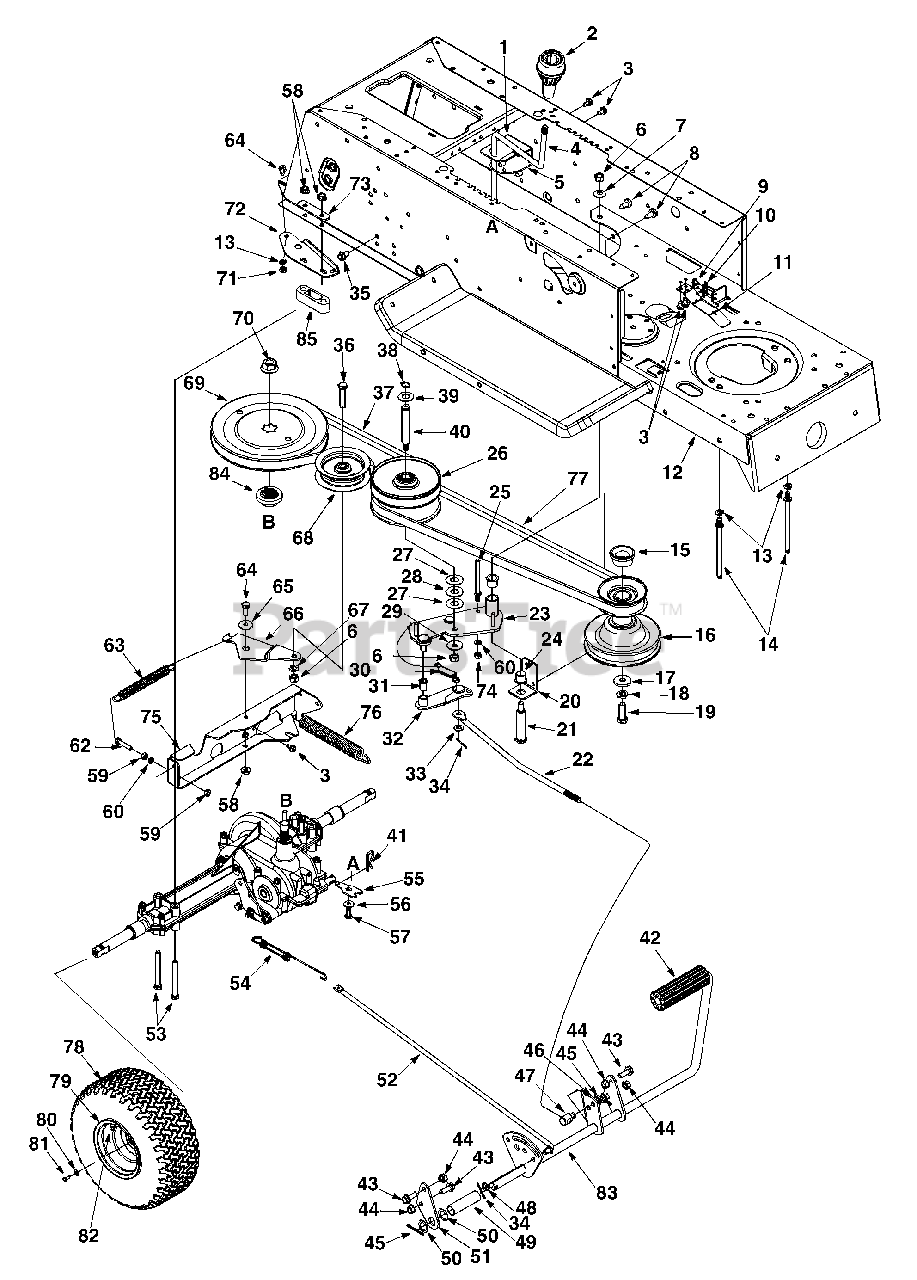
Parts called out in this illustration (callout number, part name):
2	Shift Knob
3	Self Tap. Screw 1/4-20 x .50" Lg.
4	Shift Lever Assembly
5	Comp. Spring-Clip
6	Hex Nut 3/8-24 Thd.
7	Bell Wash. .375" I.D.
8	AB-Tap Scr. 5/16-18 x .75" Lg.
9	AB-Tap Scr. #10-16 x .5" Lg.
10	Switch Plate
11	Switch Spring Actuator
13	L-Wash. 5/16" I.D.
14	Belt Guard Pin 4.75" Lg.
15	Spacer 1" I.D. x 1.25" Lg.
16	Engine Pulley
17	Fl. Wash. .450" I.D.
18	L-Wash. 7/16" I.D.
19	Hx Hd. Cap Scr. 7/16-20 x 1.25" Lg.
20	Bearing Shaft Bracket Ass'y
21	Shoulder Screw
22	Speed Control Link
25	Belt Keeper 3" Lg.
26	Variable Speed Pulley Ass'y
28	Thrust Bearing .56" I.D. x 1.25"
29	Bell Wash. .390" I.D. x 1.13"
30	Extension Spring
31	Flange Bearing
33	Fl-Wash. .344" I.D.
35	TT-Tap Scr. 5/16-18 x .625" Lg.
36	Hex Hd. Cap Scr. 3/8-24 x 1.75" Lg.
37	V-Belt
38	Snap Ring .56" Dia.
39	Fl-Wash. .570" I.D. x .120" Lg.
40	Shaft .56" Dia. x 3.79" Lg.
41	Internal Cotter Pin
42	Foot Pad
43	TT-Tap Scr. 5/16-18 x .75"
44	Sems Nut 5/16-18
45	Cotter Pin 1/8- 1.25
46	Fl-Wash .385" I.D. x .62" O.D.
47	Ferrule
48	Fl-Wash. .385" I.D. x .62" O.D.
50	Fl-Wash. .635" I.D. x .930 O.D.
53	Hex Hd. Cap Scr. 5/16-18
54	Ext. Spring
55	Shift Link Assembly
56	Bell Wash. .265 x .75
57	Hex Hd. Cap Screw 1/4-28
58	Flange L-Nut 5/16-18 Thd.
59	Hex Nut 1/4-28 Thd.
60	L-Wash. 1/4" I.D.
62	Hex Hd. Cap Screw 1/4-28
63	Extension Spring
64	Hex Hd. Cap Screw 5/16-18
65	Shoulder Spacer
67	L-Wash. 3/8" I.D.
68	Flat Idler Pulley
69	V Pulley
70	Flange Nut 9/16
71	Hex Nut 5/16-18 Thd.
74	Hex Nut 1/4-20 Thd.
77	V-Belt
80	Bell Wash. .340 I.D. x .872 O.D.
81	Hex Hd. Cap Scr. 5/16-24
82	Air Valve (Service Only)
85	Spacer (Used w/46" Deck)
